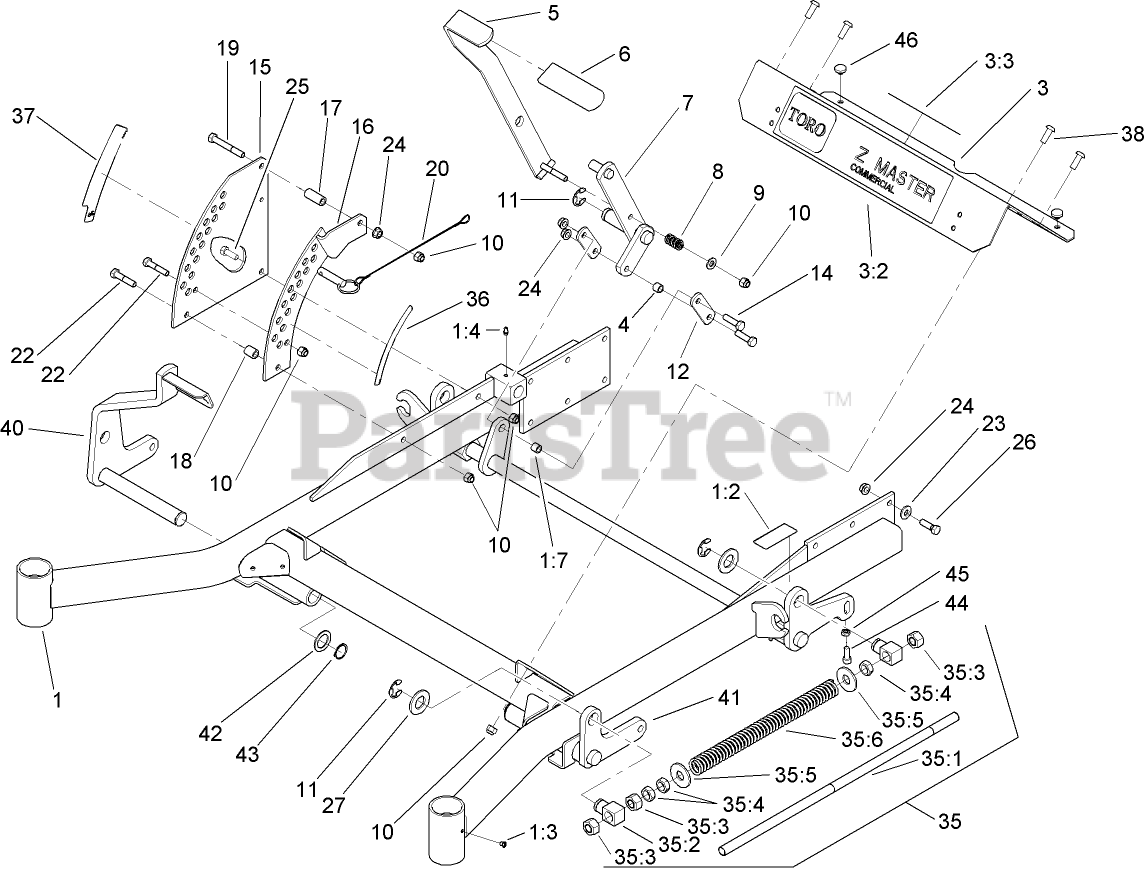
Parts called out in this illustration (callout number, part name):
1	FRONT FRAME ASM
1:2	Decal-Brake, Parking
1:4	FITTING-GREASE
1:7	Bushing
3	FOOTREST
3:3	DECAL-WARNING
4	Bushing
5	LEVER-LIFT
6	GRIP-LEVER, LIFT
7	ARM-LIFT, DECK
8	SPRING-COMPRESSION
9	WASHER-FLAT
10	NUT-LOCK, NI
11	RING-RETAINING, EXT
12	ARM-LIFT, DECK
14	SCREW-HH
15	PLATE-LIFT, DECK
16	PLATE-LIFT, DECK
17	BUSHING-LEVER, LIFT
18	BUSHING-LEVER, LIFT
19	SCREW-HH
20	Hitch Pin ASM
22	SCREW-HH
23	WASHER-BELLEVILLE
24	NUT-HHF, WHIZ
25	SCREW-HH
26	SCREW-HH
27	WASHER-FLAT
35	Front Frame Spring ASM
35:1	ROD-LIFT, DECK
35:2	SWIVEL-DECK MOUNT, REAR
35:3	NUT-HEX
35:4	NUT-JAM
35:5	WASHER-FLAT
35:6	SPRING-SUPPORT, DECK
36	Decal-Height, Deck
37	Decal-Height, Deck
38	SCREW-HSBH
40	RH Deck Lift ASM
41	LIFT-DECK, LH
42	WASHER-SPACER
43	RING-RETAINING
44	SCREW-HSH
45	NUT-JAM
46	BUMPER
